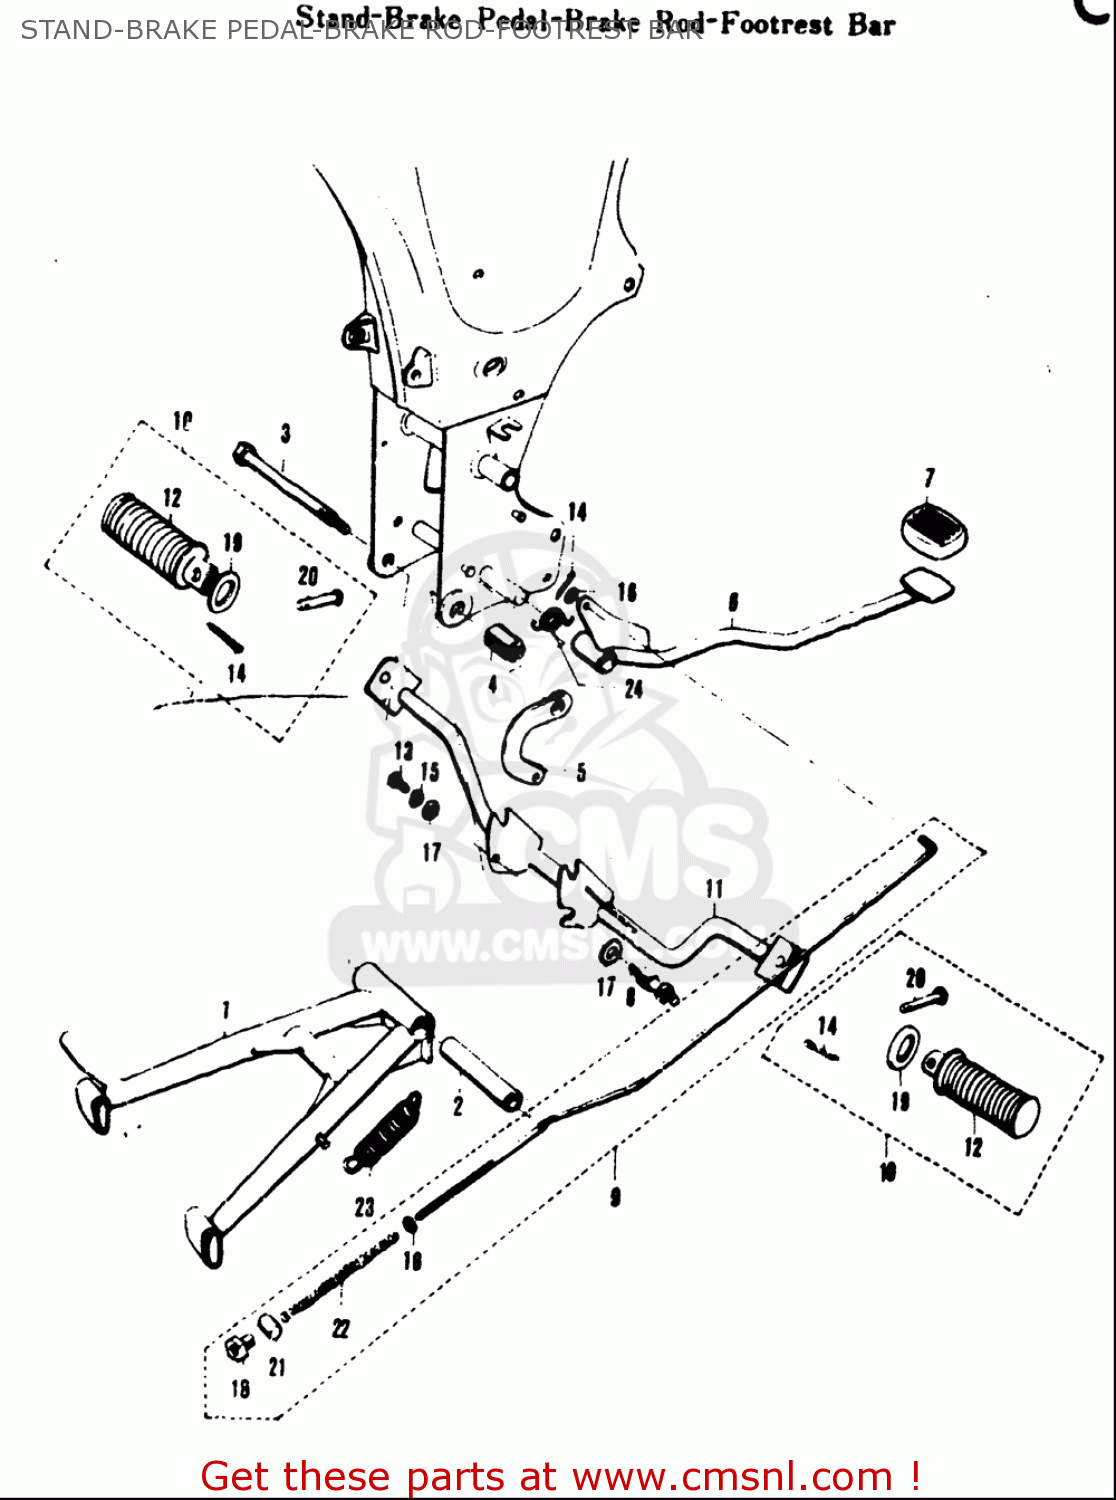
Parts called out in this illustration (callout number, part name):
2	SPACER
8	STOPPER,BRAKE PEDAL
13	BOLT
15	WASHER,LOCK
16	WASHER
17	WASHER
18	NUT
19	WASHER(22.5X38X1)
20	PIN
21	BRAKE ROD LEVER
22	SPRING
23	SPRING
